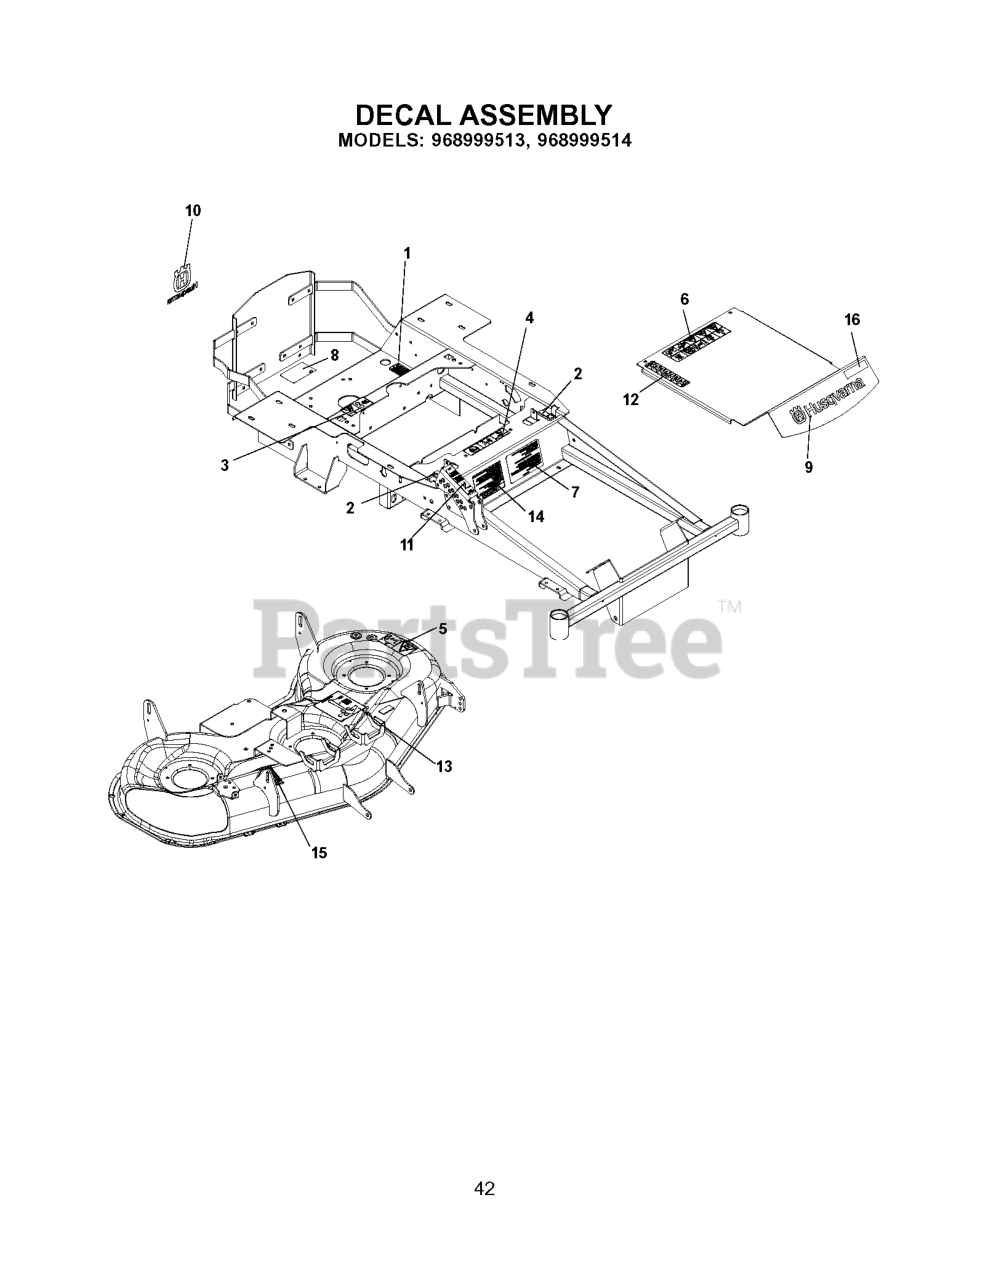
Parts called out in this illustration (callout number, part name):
1	DECAL, PROP. 65
2	DECAL, MOTION CONTROL
3	DECAL, BELT DRIVE
4	EURO DECAL-BATTERY WARNIN6
5	DECAL, EURO SEVERING
6	DECAL, WARNING
7	DECAL, START
8	DECAL, DO NOT TOW
9	DECAL, HUSQ 12" BLUE
10	DECAL, CROWN H 5-1/4 SILVER
11	DECAL, TRANS RELEASE
12	DECAL, HEIGHT ADJUST
13	DECAL, BELT ROUTING
14	DECAL, WARNING
15	DECAL, CPSC
16	DECAL, EZ4824
